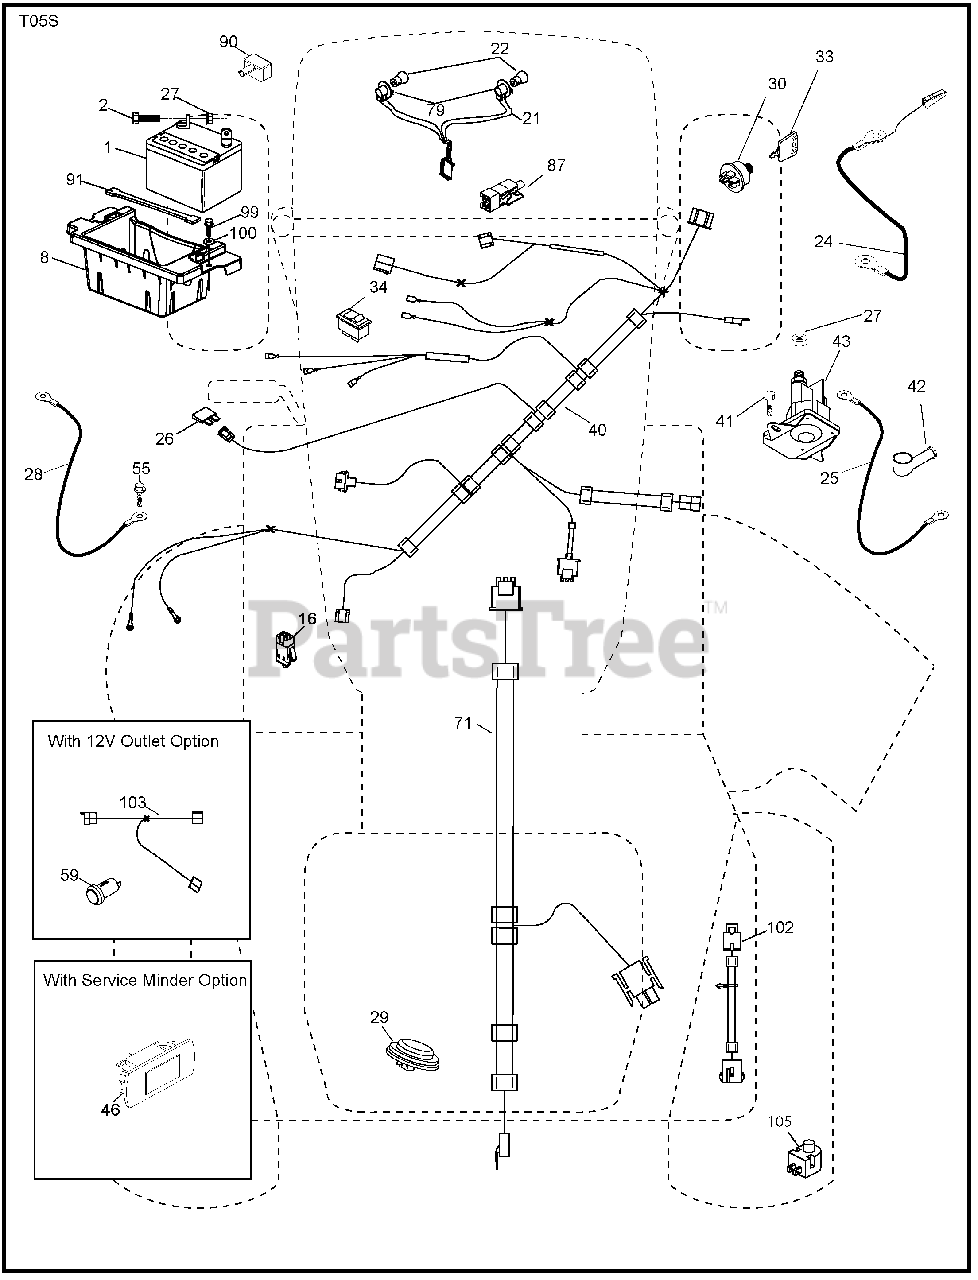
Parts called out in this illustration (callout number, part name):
1	Battery
2	Bolt Hex Head 1/4-20 x 3/4
8	Box Battery
16	Switch Interlock Push-In
21	Harness Socket Light W/4152J
22	Bulb Light
24	Cable Battery
25	Cable Starter
26	Fuse
27	Nut Keps Hex 1/4-20 unc
28	Cable, Ground
29	Switch, Seat
30	Switch, Ign
33	Key/Chain
34	Switch Light / Reset
40	Harness Ign.
41	Screw Thd Cut 1/4-20 x 1/2
42	Cover, Terminal
43	Solenoid
46	Gauge Hourmeter
55	Screw Thdrol 5/16-18 x 3/4 TYTT
71	Harness Ign. Dash
79	Socket Asm Bulb Twistlock
87	Switch Interlock Clutch Cable
90	Cover Terminal Battery
91	Strap Battery Mount Front
99	Screw Hexwsh Thdrol 1/4-20 x 3/4
100	Washer 9/32 x 7/8 x 16 Ga.
102	Harness Pigtail
105	Switch Reverse TT Pedal Control
